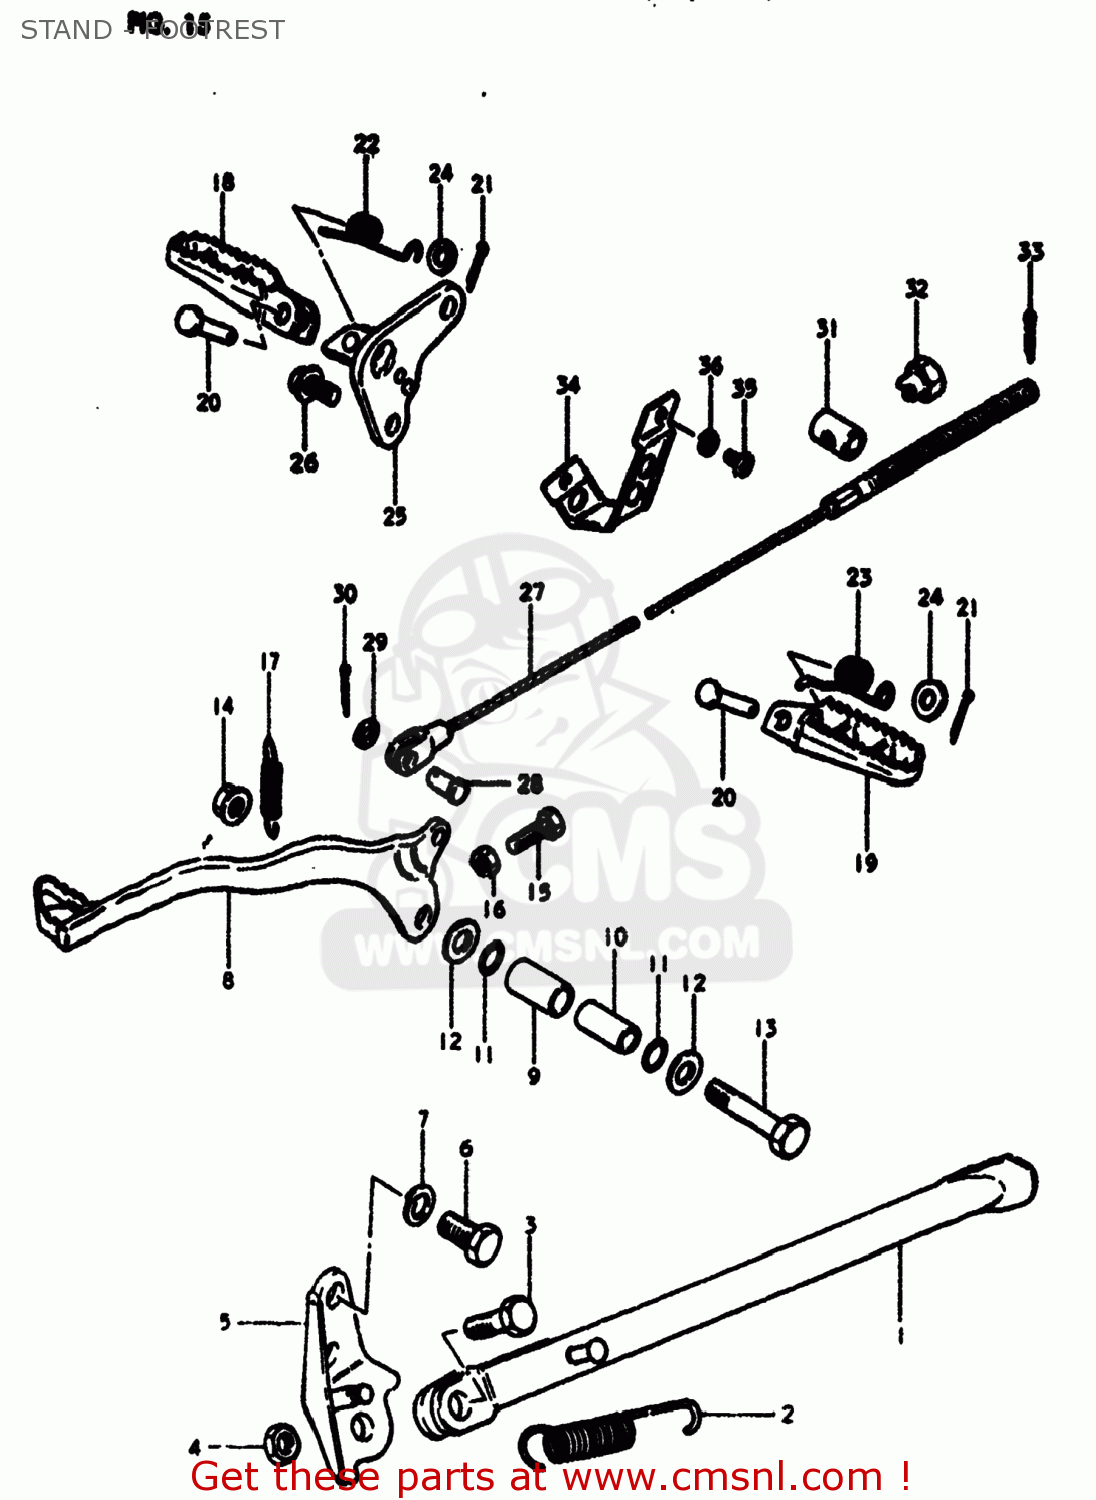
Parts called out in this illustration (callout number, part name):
1	STAND,SIDE
2	SPRING
3	BOLT(10X30)
4	NUTM10X1.25X8
5	BRACKET,PROP STAND
6	BOLT(10X19)
7	LOCK WASHER
8	PEDAL,BRAKE
9	BUSH
10	SPACER(10X14X32.2)
11	O RING(D:1.5,ID:13.8)
12	WASHER
13	BOLT
14	NUT
15	BOLT(6X23)
16	NUT
17	SPRING
18	RUBBER,FRONT FOOTREST
19	FOOTREST
20	PIN
21	PIN 30X20
22	SPRING
23	SPRING
24	WASHER
25	HOLDER,FRONT FOOTREST,RIGHT
26	BOLT(10X20)
27	CABLE,RR BRAKE
28	PIN(L:17.5)
29	WASHER
30	PIN 20X20
31	PIN
32	NUT
33	PIN
34	GUIDE,CABLE
35	SCREW
36	LOCK WASHER
